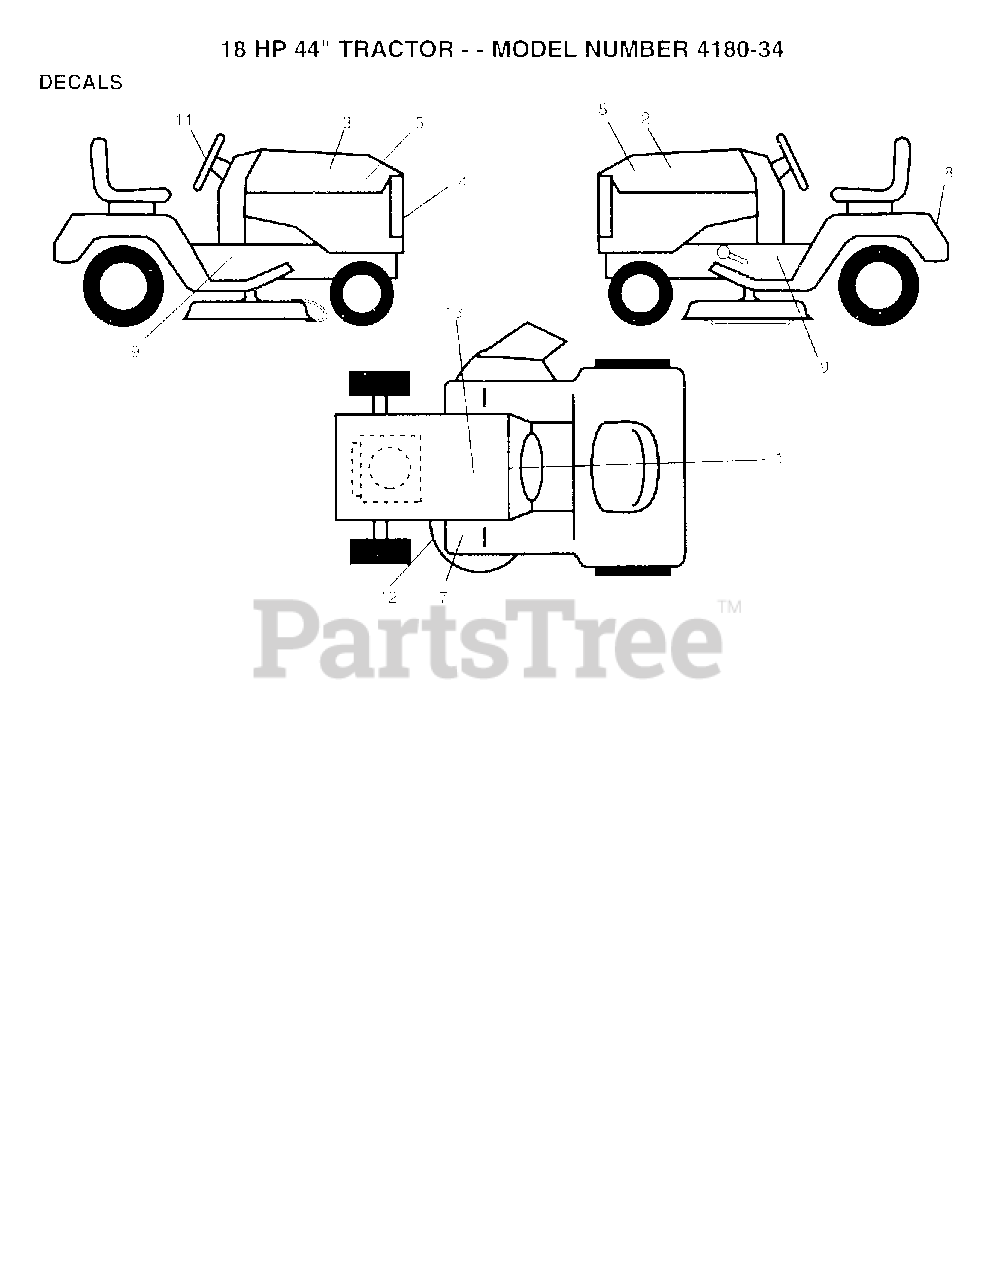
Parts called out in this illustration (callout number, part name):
2	Poulan TBD
3	Poulan TBD
4	Poulan TBD
5	Poulan TBD
8	REFLECTOR-TAIL YT
9	Poulan TBD
11	Poulan TBD
